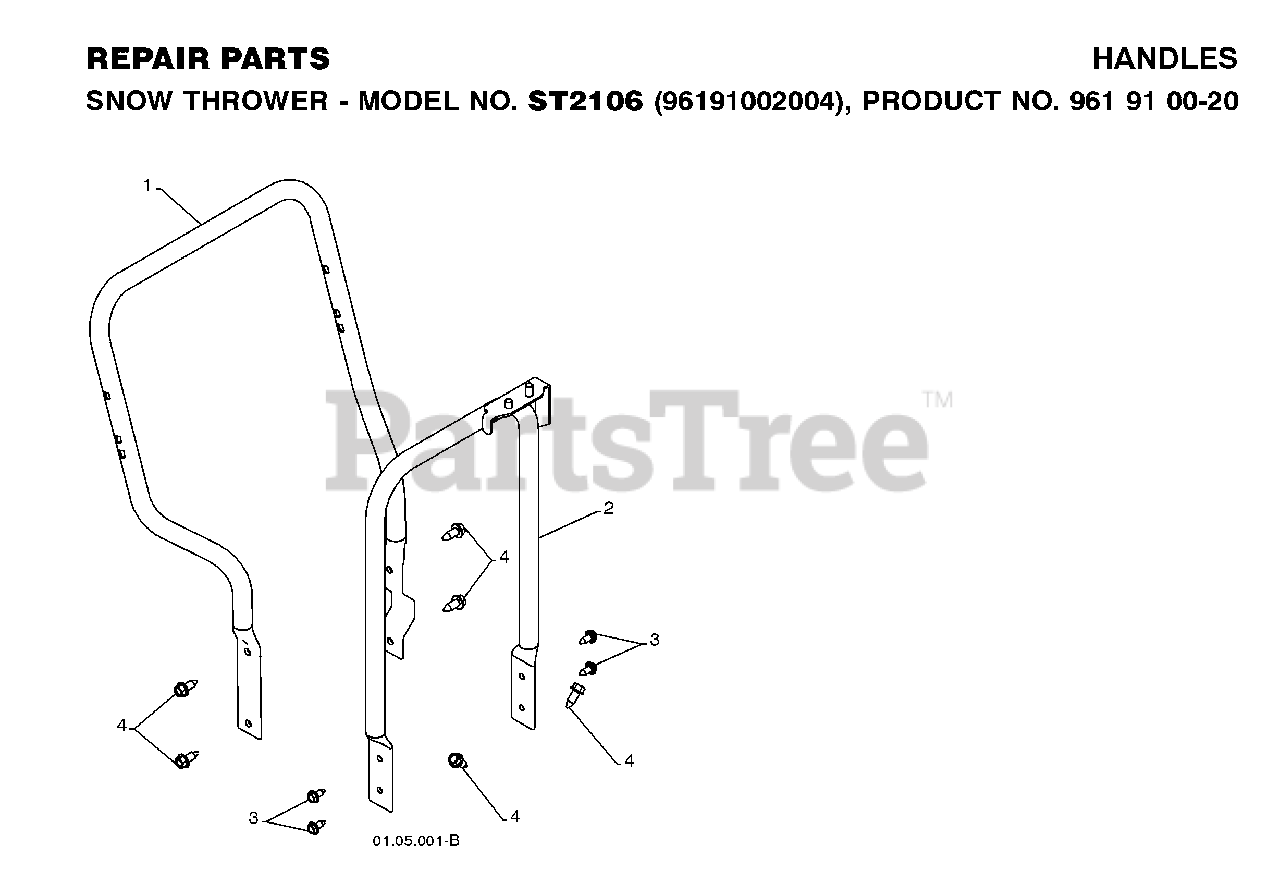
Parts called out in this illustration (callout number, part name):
2	RP PIVOT SUPPORT
3	SELF-TAPPING SCREW 5/16-18X3/4
4	SCREW 3/8-16X1
